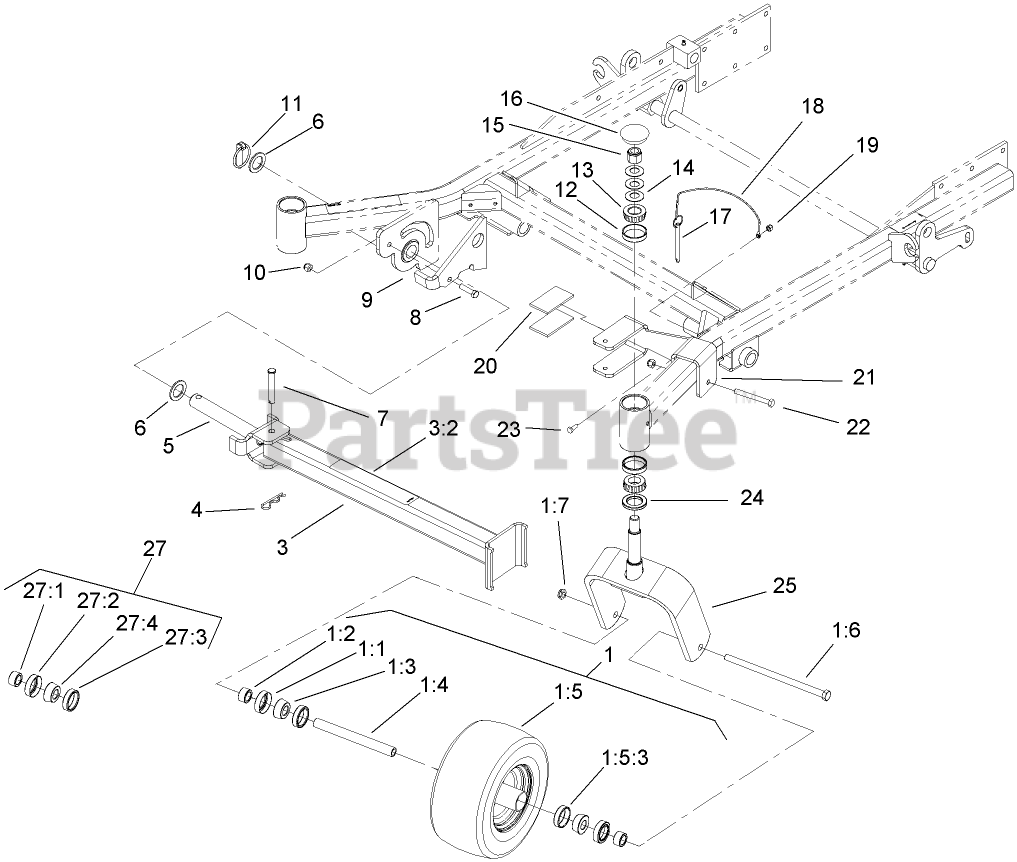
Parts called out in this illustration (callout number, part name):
1	CASTOR WHEEL ASM
1:1	SEAL-BEARING
1:2	SPACER-BEARING
1:3	BEARING-CONE, TAPER
1:4	SPACER-CASTER, FRONT
1:5	WHEEL AND TIRE ASM (SEMI-PNEUMATIC)
1:5:3	BEARING-CUP
1:6	SCREW-HH
1:7	NUT-LOCK, NI
3	Leg ASM
3:2	DECAL-Z STAND
4	PIN-HAIR
5	PIN-PIVOT
6	WASHER-THRUST
7	PIN-CLEVIS
8	SCREW-HH
9	BRACKET-LATCH
10	NUT-LOCK, NI
11	PIN-LYNCH
12	BEARING-CUP, TAPERED
13	BEARING-CONE, TAPERED
14	WASHER-BELLVILLE
15	NUT-LOCK, NI
16	CAP-GREASE
17	PIN-HITCH, COTTERLESS
18	LANYARD-NYLON
19	NUT-LOCK, NI
20	Cushion-Rubber
21	BRACKET-CRADLE
22	SCREW-HH
23	SCREW-HH
24	SEAL-GREASE
25	CASTER-FORK
27	CASTER WHEEL BEARING KIT
27:1	SPACER-BEARING
27:2	SEAL-BEARING
27:3	BEARING-CUP
27:4	BEARING-CONE, TAPER
